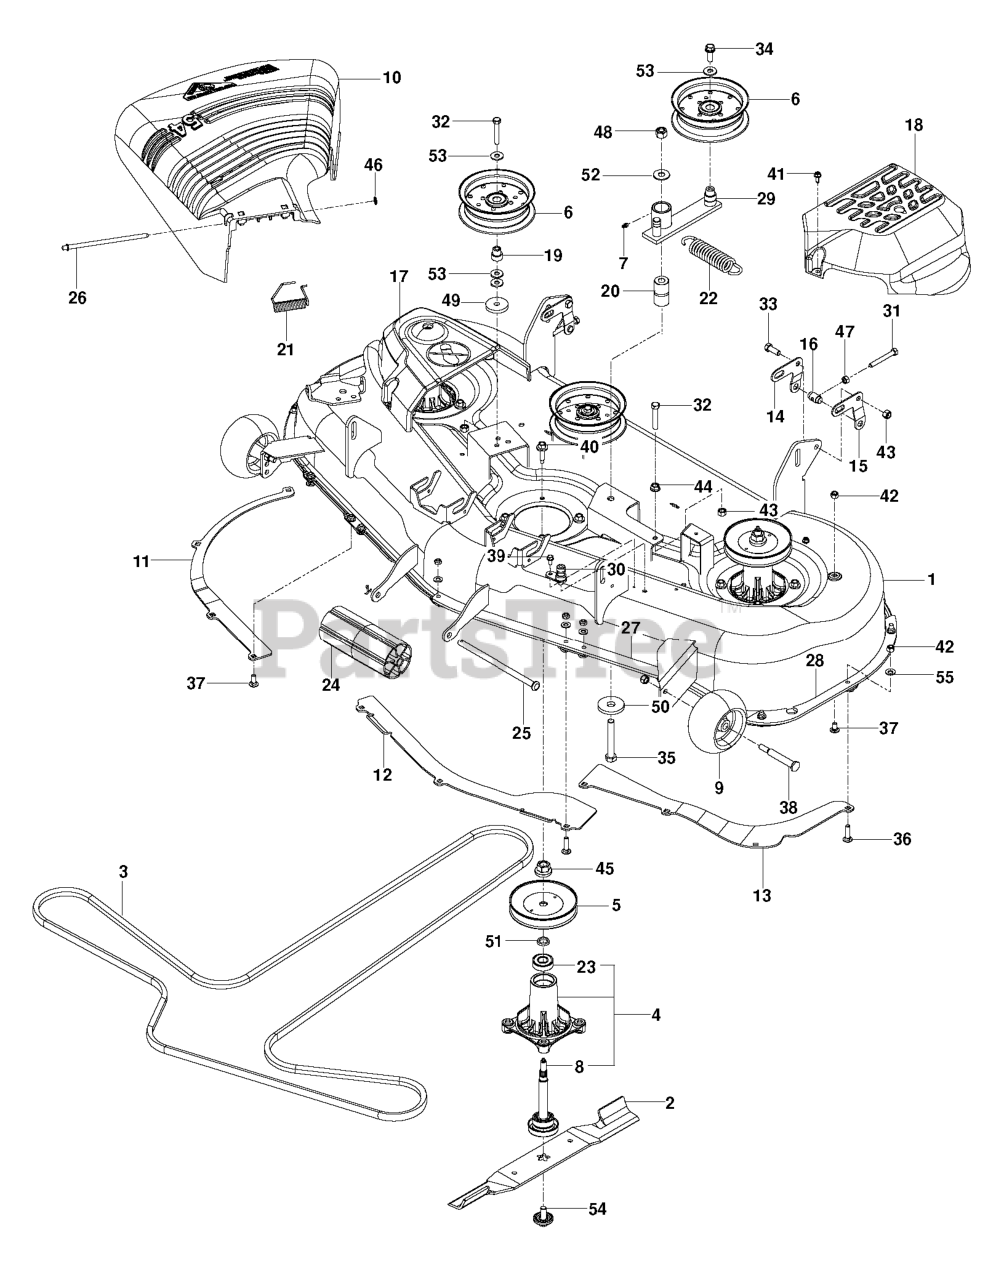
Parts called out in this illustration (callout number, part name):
1	DECK.SVC W/DECALS.54.MZ.ORANGE
2	BLADE.BAGGING.54"
3	BELT.DECK.EL=152.9
4	MANDREL GREASABLE
5	PULLEY
6	PULLEY, IDLER
7	ZERK
8	GREASABLE MANDREL SHAFT
9	WHEEL GAGE DONUT
10	DEFLECTOR.BLACK.54"
11	BAFFLE.RIGHT.54"
12	BAFFLE CENTER 54" MOWER
13	BAFFLE.LEFT.54"
14	BRACKET.RT.PNT.MS431
15	BRACKET.LH.PNT.MS431
16	TRUNION, PITCH
17	COVER.MANDREL.RH.DECK.54"
18	COVER.MANDREL.LH.DECK.54"
19	IDLER BUSHING
20	PIVOT BUSHING
21	SPRING, TORSION
23	BEARING, BALL
24	NOSE ROLLER 48"
25	ROD.ROLLER.NOSE.NARROW.48"
26	ROD.HINGE
27	PLATE.REIN.FRONT.BOLT54"X431
28	PLATE.REIN.SIDE.BOLT.54"X431
30	PORT.WASHOUT
31	SCREW.HCS 5/16-18 X 3 GR 5
32	CAP.SCREW.HEX.HD.3/8-16
33	HCS 3/8-16X1.GRD.5.ZD
34	4CS 3/8C X 1 SERRATED HEAD
35	HCS 1/2C X 3 1/4
36	BOLT, CARRIAGE 5/16X1-1/4
37	CARRIAGE BOLT 5/16C X 5/8"
38	BOLT.SHOULDER.3/8-16X3-5/8.
39	BOLT 1/4-20 X 1/2 HWST
40	SCREW, WASHER HEAD
41	SCREW- 1/4-20 X 5/8
42	LOCKNUT
43	NUT 3/8-16 NYLOC
44	NUT 3/8C WHIZ
45	NUT.FLANGE.LOCK.TOP
46	PUSH NUT
47	NUT 5/16C HEX
48	NUT 1/2-13 HEX NYLOC ZD
49	SPINDLE WASHER
50	WASHER, SUPPORT
51	WASHER.SPACER.MANDREL
52	WASHER 1/2 FLAT
53	WASHER 3/8 FLAT
54	BOLT.WASHER.ASM.7/16-2
55	WASHER
